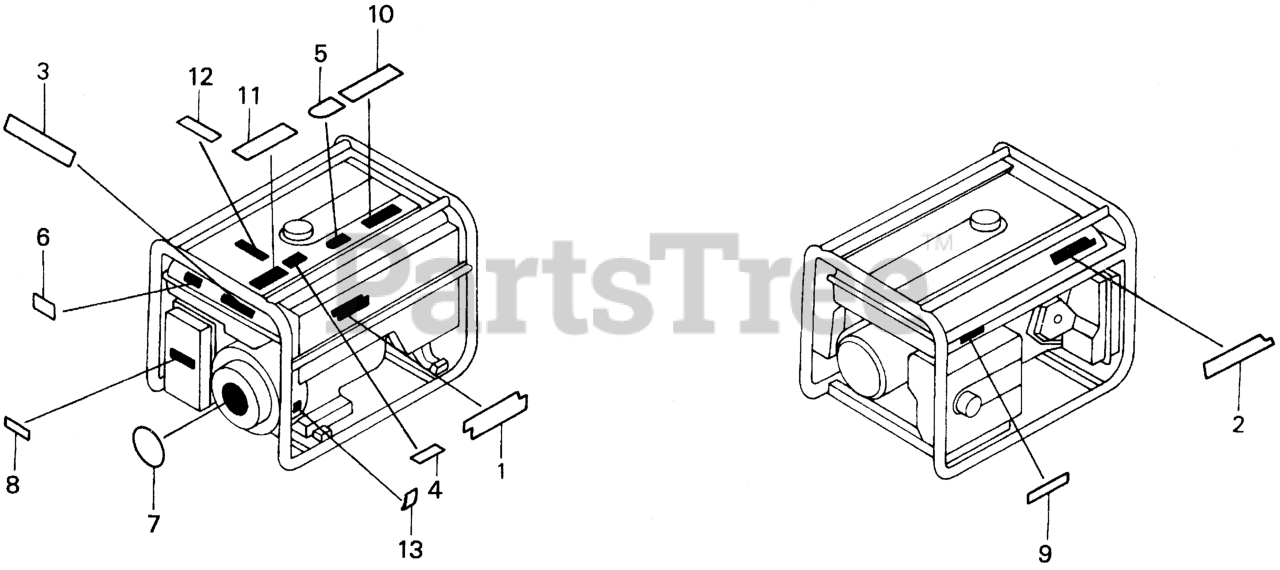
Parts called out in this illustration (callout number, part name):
1	MARK, EMBLEM (EB) (NOT AVAILABLE)
2	MARK, HONDA (NOT AVAILABLE)
3	PLATE, CAUTION
4	LABEL, RAIN WARNING (ENGLISH)
5	MARK, CAUTION (ENGLISH/FRENCH)(SPANISH)
6	MARK, CHOKE
7	MARK, OIL ALERT (NOT AVAILABLE)
8	MARK, AIR CLEANER (ENGLISH)
9	MARK, EX. CAUTION (ENGLISH/FRENCH)
10	MARK, CAUTION (CO)(ENGLISH/FRENCH)(SPANISH)
11	LABEL, CONNECT WARNING (ENGLISH)
13	MARK, OIL CAUTION
